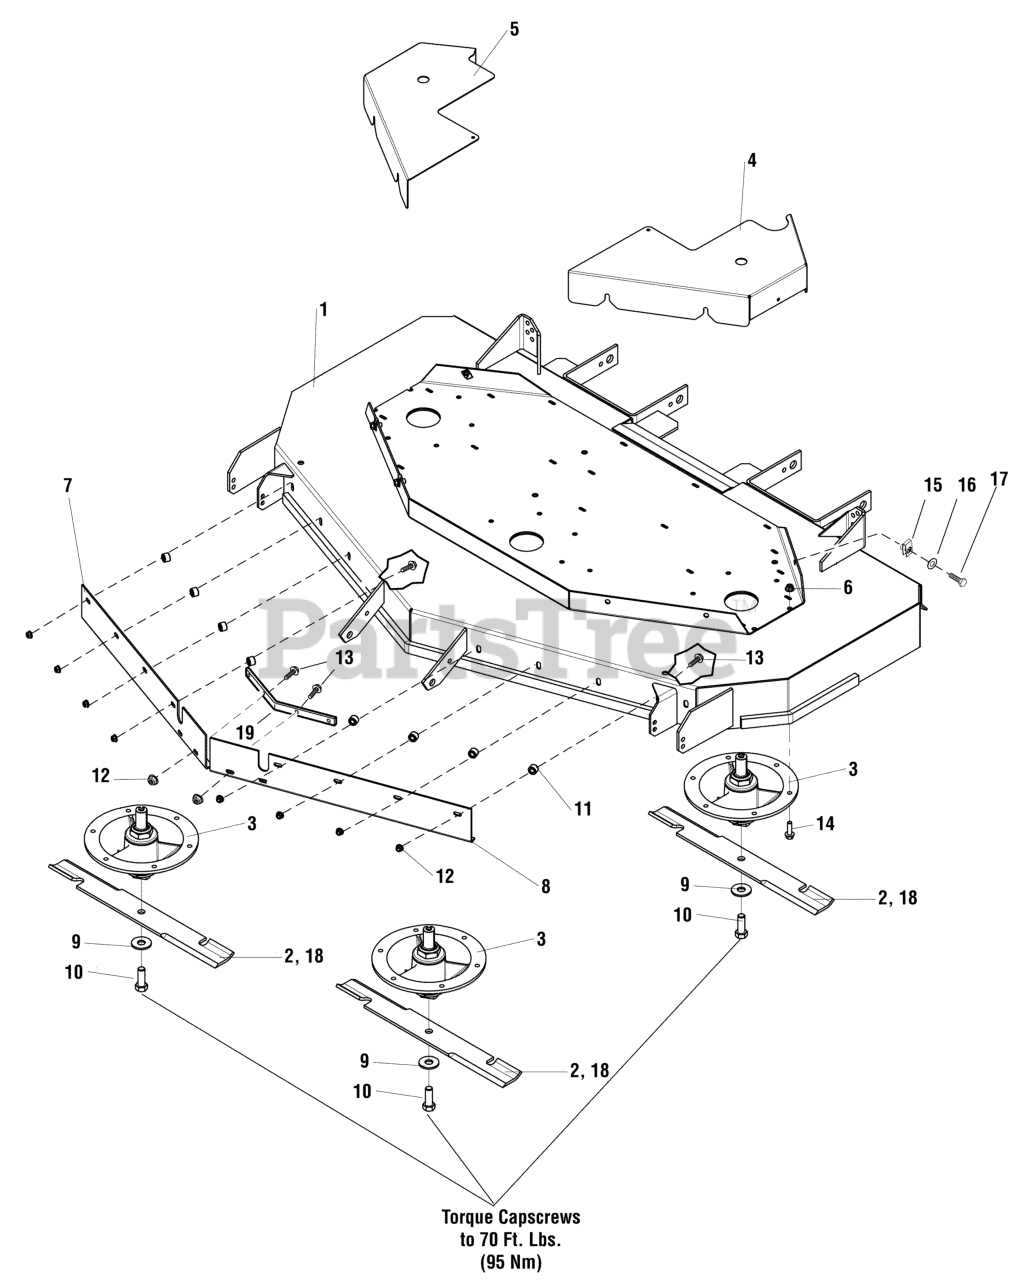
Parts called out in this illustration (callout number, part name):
1	DECK SHELL W/DECALS, 61" RD - DOMESTIC
1	DECK SHELL W/DECALS, 61" RD - EXPORT
1	DECK SHELL W/DECALS, 72" RD
2	BLADE, 21"
2	BLADE, 25" (SET OF THREE)
3	SPINDLE ASSEMBLY
4	GUARD, 61" 5000 - LH - RED
4	GUARD, DECK - LH - RED
5	GUARD, 61" 5000 - RH - RED
5	GUARD, DECK - RH - RED
6	NUT, 3/8-16 HEX NYLOCK FLANGE
7	BAFFLE, BLOWOUT, RH
8	BAFFLE, BLOWOUT, LH
9	WASHER, 5/8" GRADE 8, YZ
10	BOLT, 5/8-11 X 1-3/4 GR8
11	SPACER, .39 X .75 X .50, CZ
12	NUT, 5/16-18 HEX NYLOCK FLANGE
13	BOLT, 5/16-18 X 3/4" FLANGE
14	BOLT, 3/8-16 X 1-1/4", FLANGE
15	BODY CLIP, 5/16-18-7GA MATERIAL
16	WASHER, 5/16" SAE
17	BOLT, 5/16-18 X 3/4 GD5
18	BLADE, 21", SAND
18	BLADE, 25", SAND
19	BAFFLE, REINFORCEMENT - BLK
